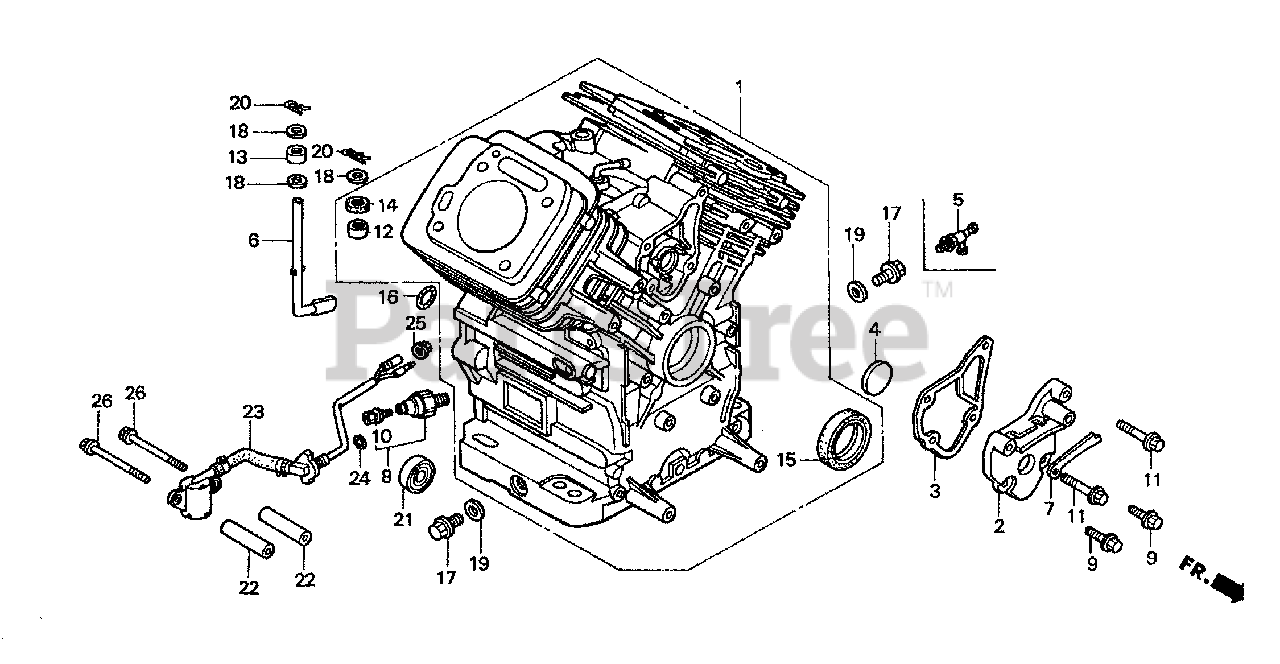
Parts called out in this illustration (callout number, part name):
1	CYLINDER ASSY.
2	COVER, BREATHER
3	GASKET, BREATHER COVER
4	VALVE, BREATHER
5	VALVE, DRAIN (14X1.5)
6	SHAFT, GOVERNOR ARM
7	CLAMP, WIRE
8	SWITCH, OIL PRESSURE
9	BOLT, FLANGE (6X16)
10	SCREW-WASHER (4X8)
11	BOLT, FLANGE (6X32)
12	BEARING, NEEDLE (8X12.7X11.1)
13	BEARING, NEEDLE (8X12X10)
14	OIL SEAL (8X14X5)
15	OIL SEAL (38X58X9)
16	O-RING (13X3.0)
17	BOLT, DRAIN PLUG (14MM)
18	WASHER, PLAIN (8MM)
19	WASHER, DRAIN PLUG (14MM)
20	PIN, LOCK (8MM)
21	BEARING, RADIAL BALL (6003)
